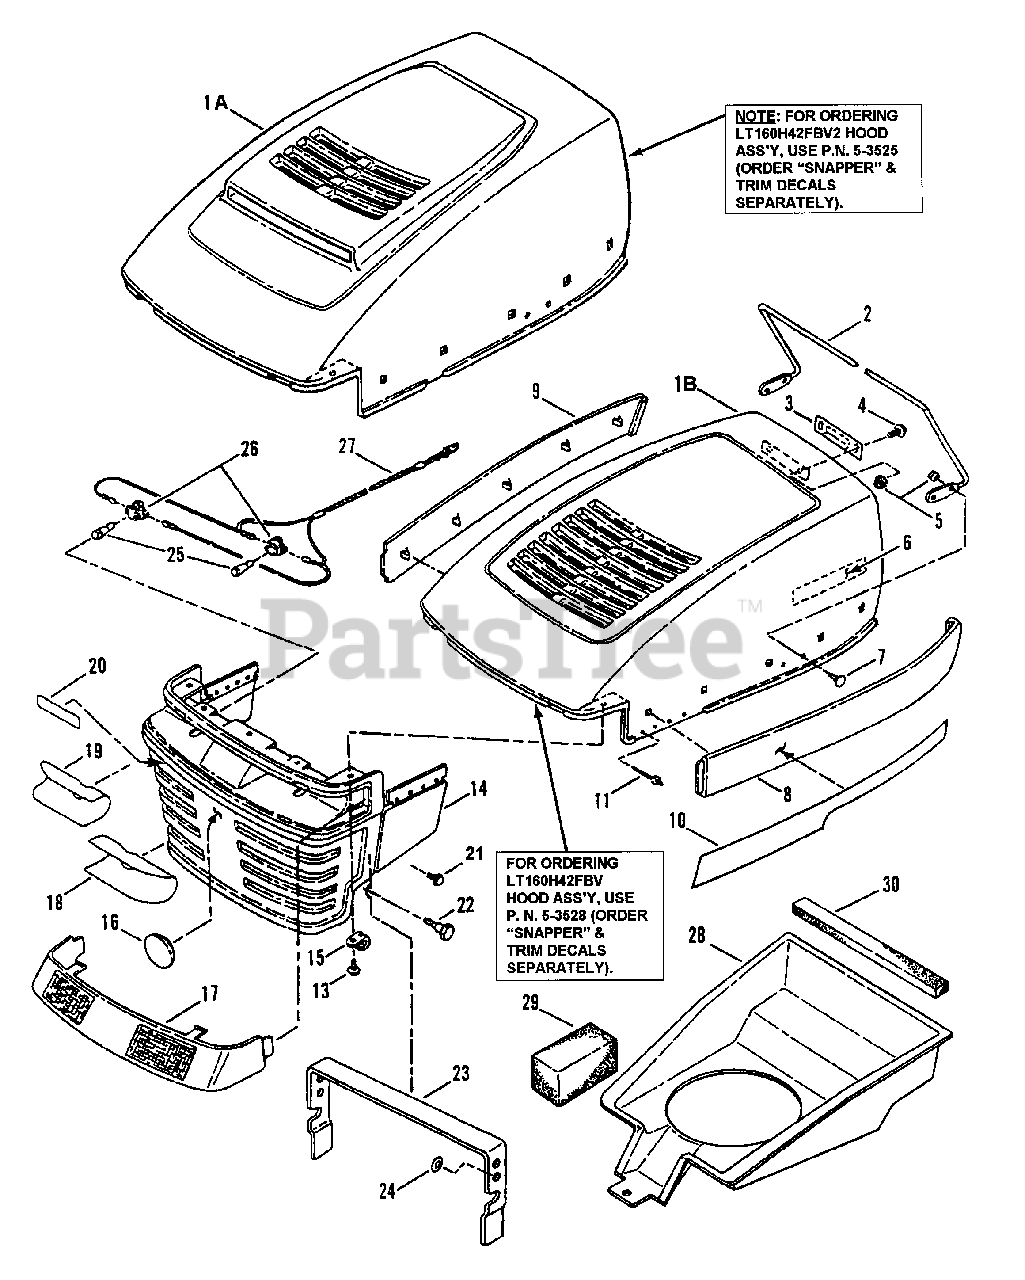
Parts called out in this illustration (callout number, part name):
1A	HOOD, Mozart (with Scoop)
1B	HOOD, Mozart
2	ROD, Hood Support
3	LATCH, Spring
4	SCREW, 1/4-20 x 5/8" Truss Head, Torx
5	NUT, 1/4-20 Hex Nyloc
6	DECAL, SNAPPER, 8" Molded Logo
7	BOLT, 1/4-20 x 5/8" Flat Head Carriage
8	PANEL, Hood (Left Hand)
9	PANEL, Hood (Right Hand)
10	DECAL, Hood (Right Hand)
10	DECAL, Hood (Left Hand)
11	RIVET, 1/8" Pop
13	SCREW, M4.8 x 1.59 x 16.00mm
14	GRILLE, Hood
15	CLIP, "J"
16	DECAL, Molded Medallion
17	LENS, Grille (Headlights)
18	DECAL, Reflect (Left Hand)
19	DECAL, Reflect (Right Hand)
20	DECAL, SNAPPER, 4" Molded Logo (Silver Letters - Blue Stripe)
21	SCREW, 5/16-18 x 1/2" Self-Tapping
22	BOLT, Shoulder, 3/8-16 x 1-1/4" Hex Socket, Torx
23	BRACE, Hood Support
24	RETAINER, 5/16" Bolt
25	BULB, Headlights
26	SOCKET, Headlight Bulb
27	HARNESS, Headlight Wiring
28	PLENUM
29	FOAM, 2 x 2 x 3.5"
30	FOAM, 1/2 x 3/4 x 14.25"
53525	HOOD ASSY
53528	HOOD ASSY
